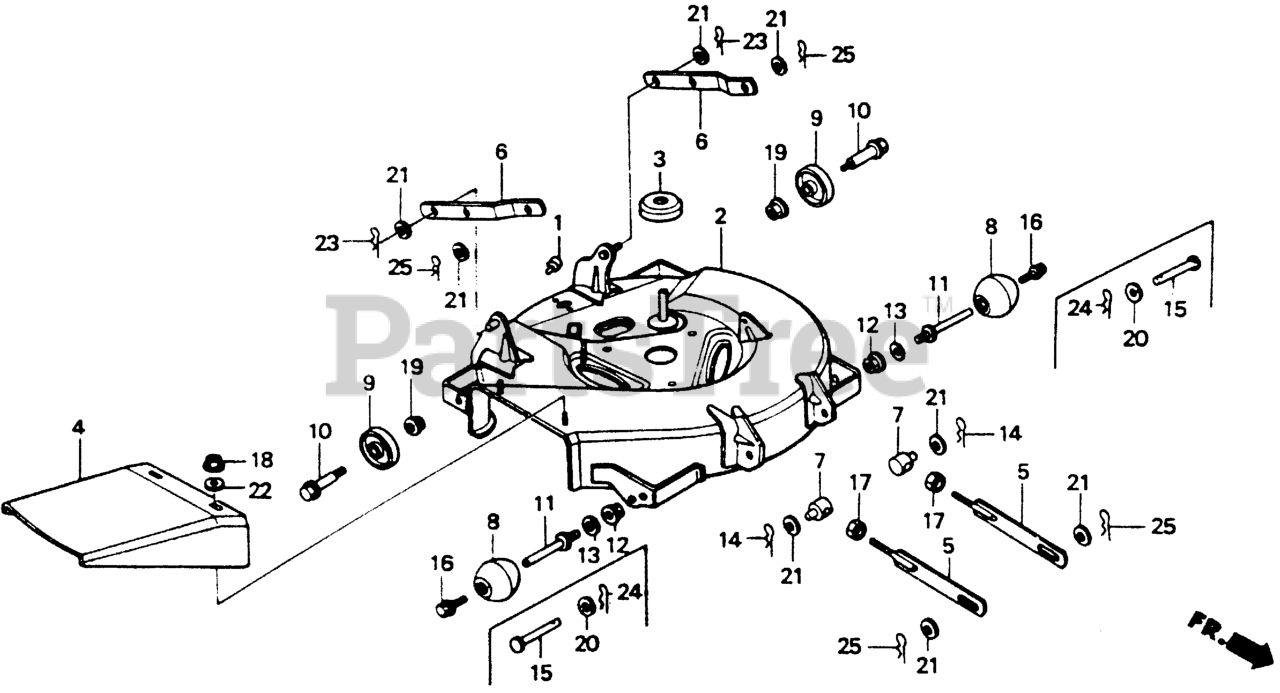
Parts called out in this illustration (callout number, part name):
1	RUBBER, STOPPER
2	HOUSING, CUTTER (NOT AVAILABLE)
3	CAP, TENSION ARM
4	ADAPTER, DISCHARGE *NH190M* (VINTAGE GRAY METALLIC) (NOT AVAILABLE)
5	LINK, FR. DECK
6	LINK, RR. DECK
7	PIN, FR. LINK ADJUSTING
8	ROLLER, ANTI-SCALP
9	ROLLER, RR. ANTI-SCALP
10	BOLT, ANTI-SCALP ROLLER
11	SHAFT, ANTI-SCALP ROLLER
12	NUT, FLANGE (12MM)
13	WASHER, SPECIAL (12MM) (NOT AVAILABLE)
14	PIN, LOCK (2.3MM)
16	BOLT-WASHER (8X12)
16	BOLT-WASHER (8X16)
17	NUT, HEX. (12MM)
18	NUT, FLANGE (8MM)
19	NUT, FLANGE (10MM)
21	WASHER, PLAIN (14MM)
22	WASHER, PLAIN (8MM) (NOT AVAILABLE)
23	PIN, COTTER (4X25)
25	PIN, LOCK (14MM)
